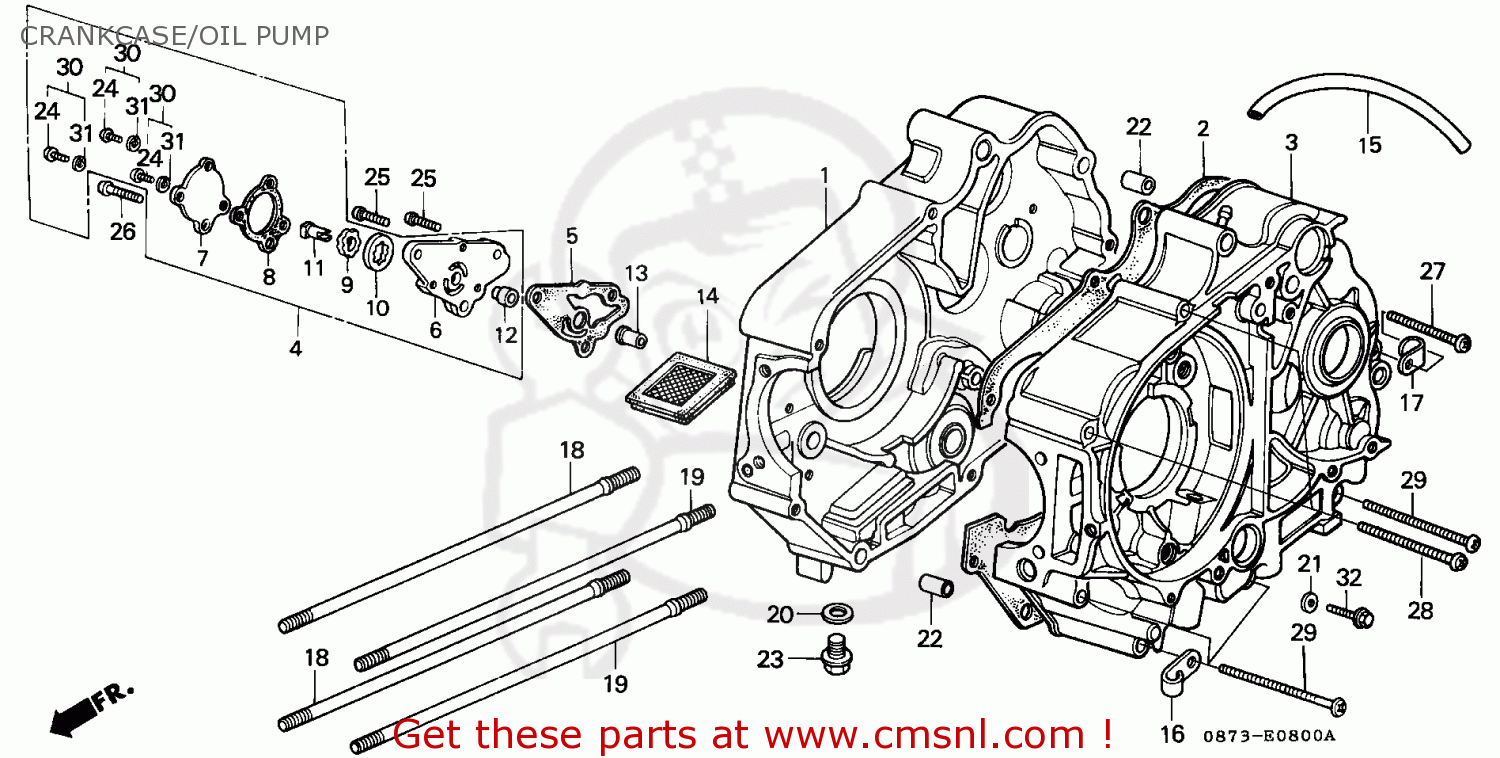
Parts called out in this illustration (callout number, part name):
1	CRANKCASE COMP,R.
2	GASKET,CRANK CASE (MCA)
3	CRANKCASE COMP.,L
4	PUMP ASSY,OIL
5	GASKET (NAS)
6	PUMP BODY,OIL
7	COVER, OIL PUMP
8	GASKET, COVER (NAS)
9	ROTOR, OIL PUMP
10	ROTOR, OIL PUMP
11	SHIFT, OIL PUMP
12	KNOCK,DIL PUMP
14	SCREEN, FILTER
16	CLAMPER,OVER FLOW
18	STUD A, CYLINDER
19	STUD B, CYLINDER
20	PACKING, COCK
22	PIN, KNOK 10X14
23	BOLT DRAIN 12MM
24	SCREW,CROSS 5X10
25	SCREW,PAN,6X16
26	SCREW,PAN 6X22
27	BOLT,FLANGE,6X50
28	SCREW CROSS 6X63
29	BOLT,FLANGE,6X65
31	WASHER,SPG.,5MM
